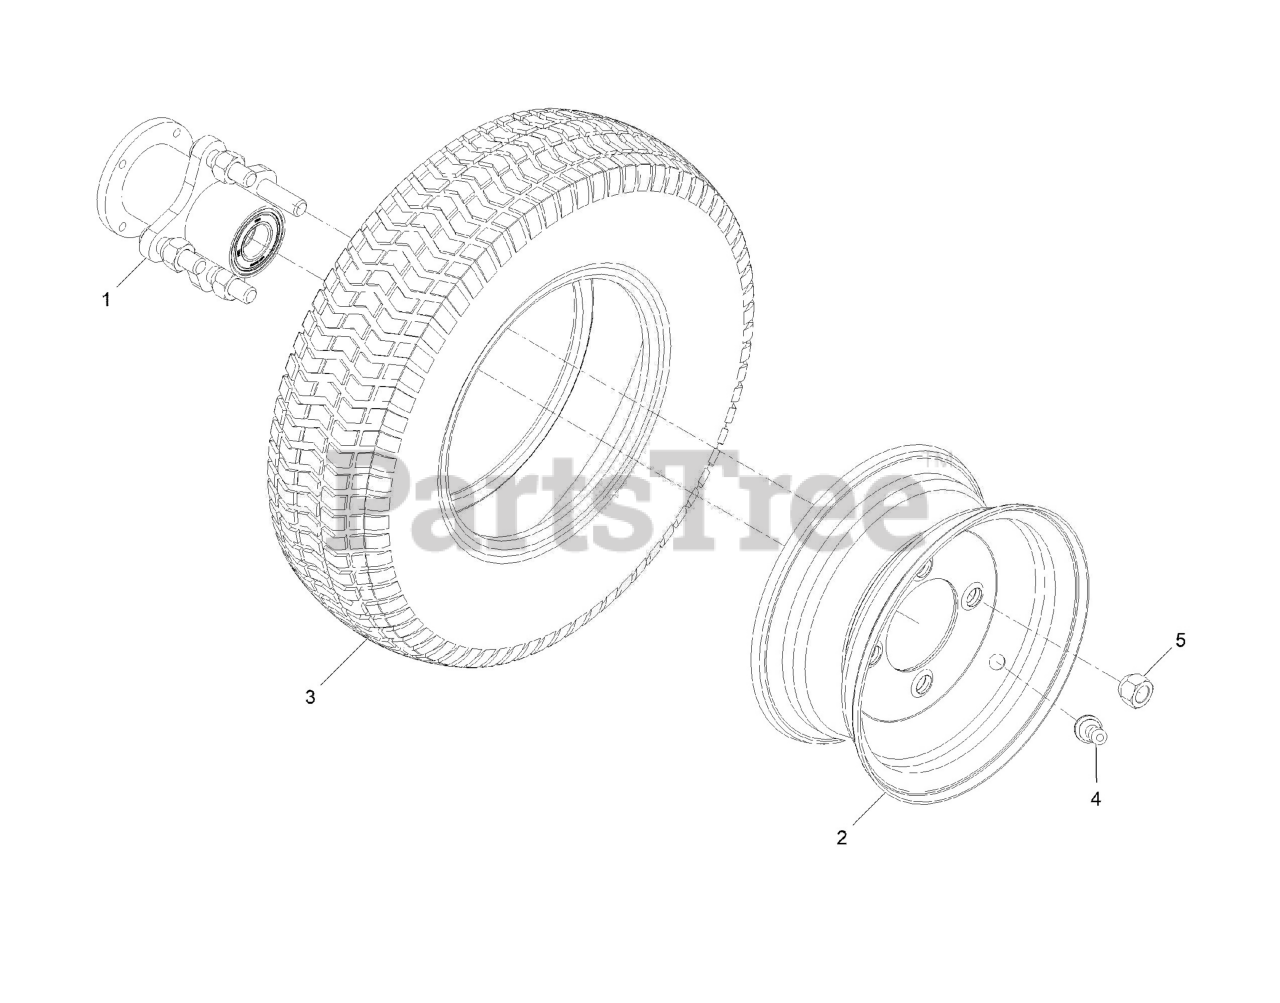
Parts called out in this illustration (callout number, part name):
1	Wheel Hub ASM
2	Rim
3	Tire
4	Stem-Valve
5	NUT-LUG
